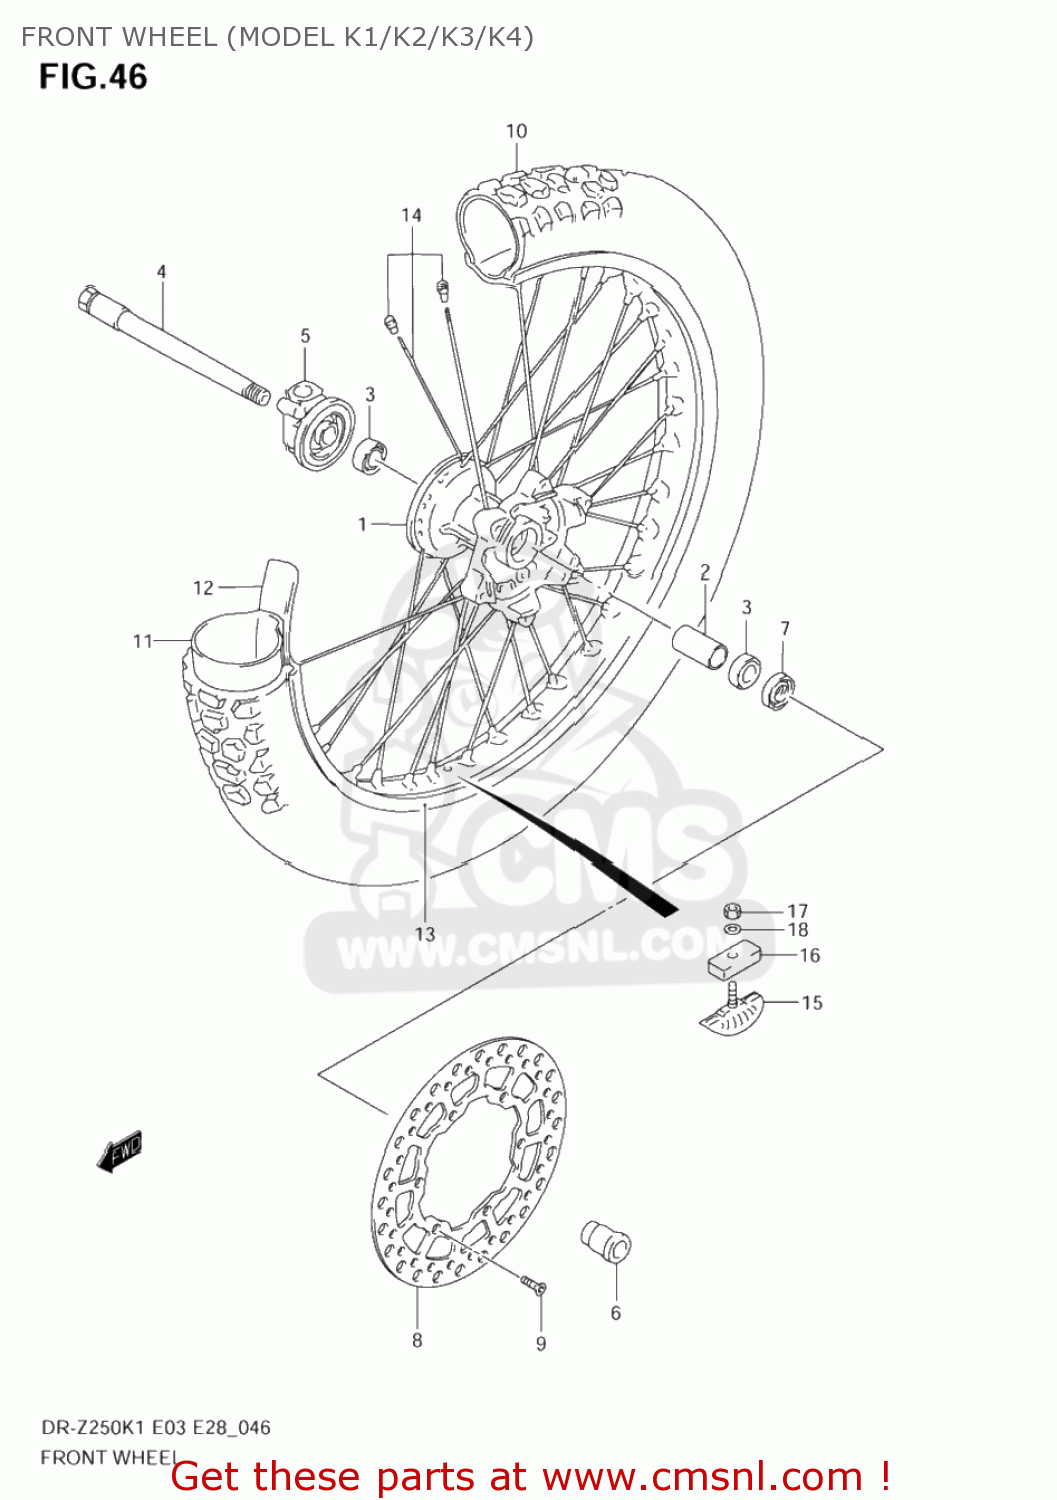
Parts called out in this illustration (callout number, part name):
1	HUB,FR WHEEL
2	SPACER,FR HUB BEARING
3	BEARING
4	AXLE,FR
5	BOX ASSY,SPEEDOMETER GEAR
6	SPACER,FR AXLE,L
7	SEAL,OIL(23X35X6)
8	DISC,FR BRAKE,L
9	SCREW
10	TIRE,FR(80/100-21 51M D739F)
11	TUBE ASSY,WHEEL INNER
12	PROTECTOR,WHL INR TUBE
13	RIM,FRONT WHEEL (1.60X2
14	SPOKE SET,FR WHEEL
15	STOPPER,BEAD
16	CUSHION,BEAD STOPPER
17	NUT
18	WASHER
